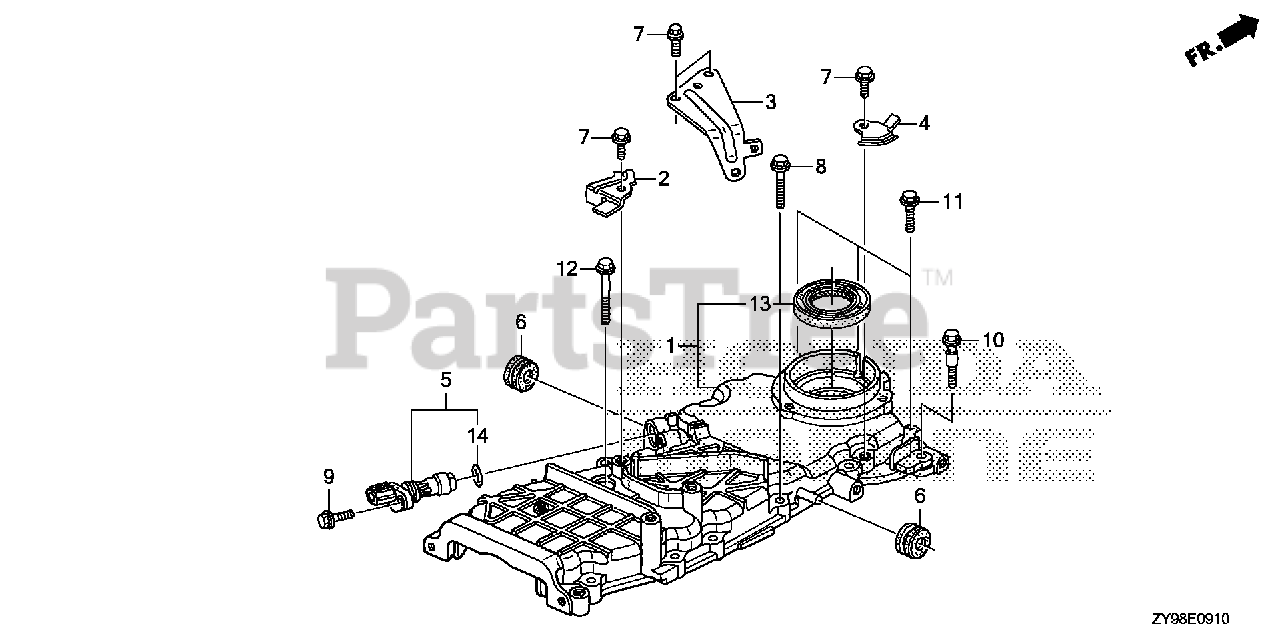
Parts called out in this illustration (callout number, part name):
1	CASE, CHAIN *NH8* (DARK GRAY)
2	BRACKET A, HARNESS CLIP
3	BRACKET C, HARNESS CLIP
4	BRACKET E, HARNESS CLIP
5	SENSOR ASSY., CRANK
6	GROMMET, CASE (LOWER)
7	BOLT, FLANGE (6X14) (CT200)
8	BOLT, FLANGE (6X28)
9	BOLT, FLANGE (6X16)
10	BOLT, SPECIAL (6X31)
11	BOLT, FLANGE (6X22)
12	BOLT, FLANGE (6X40)
13	OIL SEAL (40X55X7) (NOK)
14	O-RING (15X1.9)
